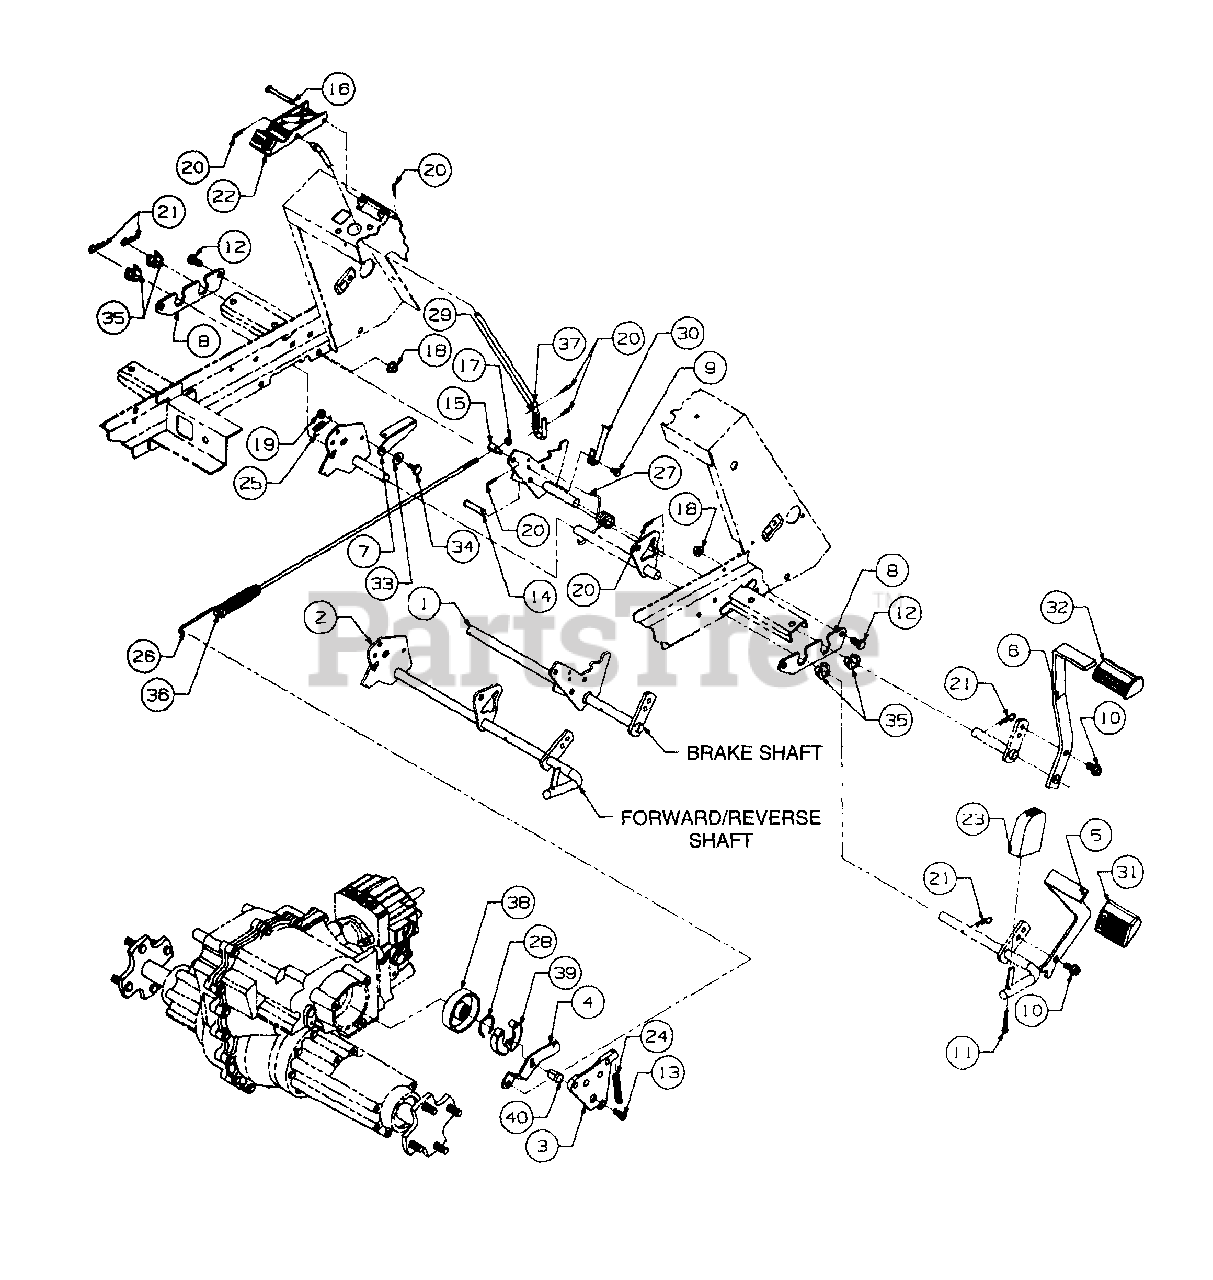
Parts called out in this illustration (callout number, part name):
1	Shaft Assy, Brake
2	Shaft Assy, Forward/Reverse
3	Plate, Brake
4	Arm, Brake
5	Pedal, Forward
6	Pedal, Brake
7	Actuator, Reverse Switch
8	Plate, Bearing Mounting
9	Screw, Hex Wash Tapp, 1/4 x .50 Lg
10	Screw, Hex Wash Tap, 3/8-16 x .75 Lg
11	Screw, Truss Mach Tapp, #12 x 1.5
12	Screw, Hex Cap, 3/8-16 x .75 GR5
13	Screw, Low Hd Cap, 3/8-16 x .75
14	Pin, Clevis, 3/8 OD x 1.62 Lg
15	Ferrule, Adjustment
16	Pin, Clevis, 1/4 OD x 2.38 Lg
17	Nut, Hex Sems, 1/4-20
18	Nut, Hex Flanged Lock, 3/8-16
19	Nut, Hex Flange Lock, 1/4-20
20	Pin, Internal Cotter, 5/16 Dia x 1.12
21	Pin, Internal Cotter, 3/8 Dia x 1.625
22	Lever, Park Brake
23	Pad, Reverse Pedal
24	Spring, Compression
25	Spring, Extension, .38 OD x 2.10 Lg
26	Spring, Extension, .75 OD x 5.0 Lg
27	Spring, Torsion
28	Spring, Brake
29	Spring, Compression, .5 OD x 2.23
30	Actuator, Neutral Switch
31	Pad, Forward Pedal
32	Pad, Brake Pedal
33	Washer, Flat, .406 x .75 x .063
34	Bolt, Shoulder, .375 Dia x .181 Lg
35	Bearing, Hex Flange Split
36	Rod, Brake
37	Rod, Park Brake Engagement
38	Drum, Brake
39	Shoe, Brake
40	Actuator, Brake Shoe
